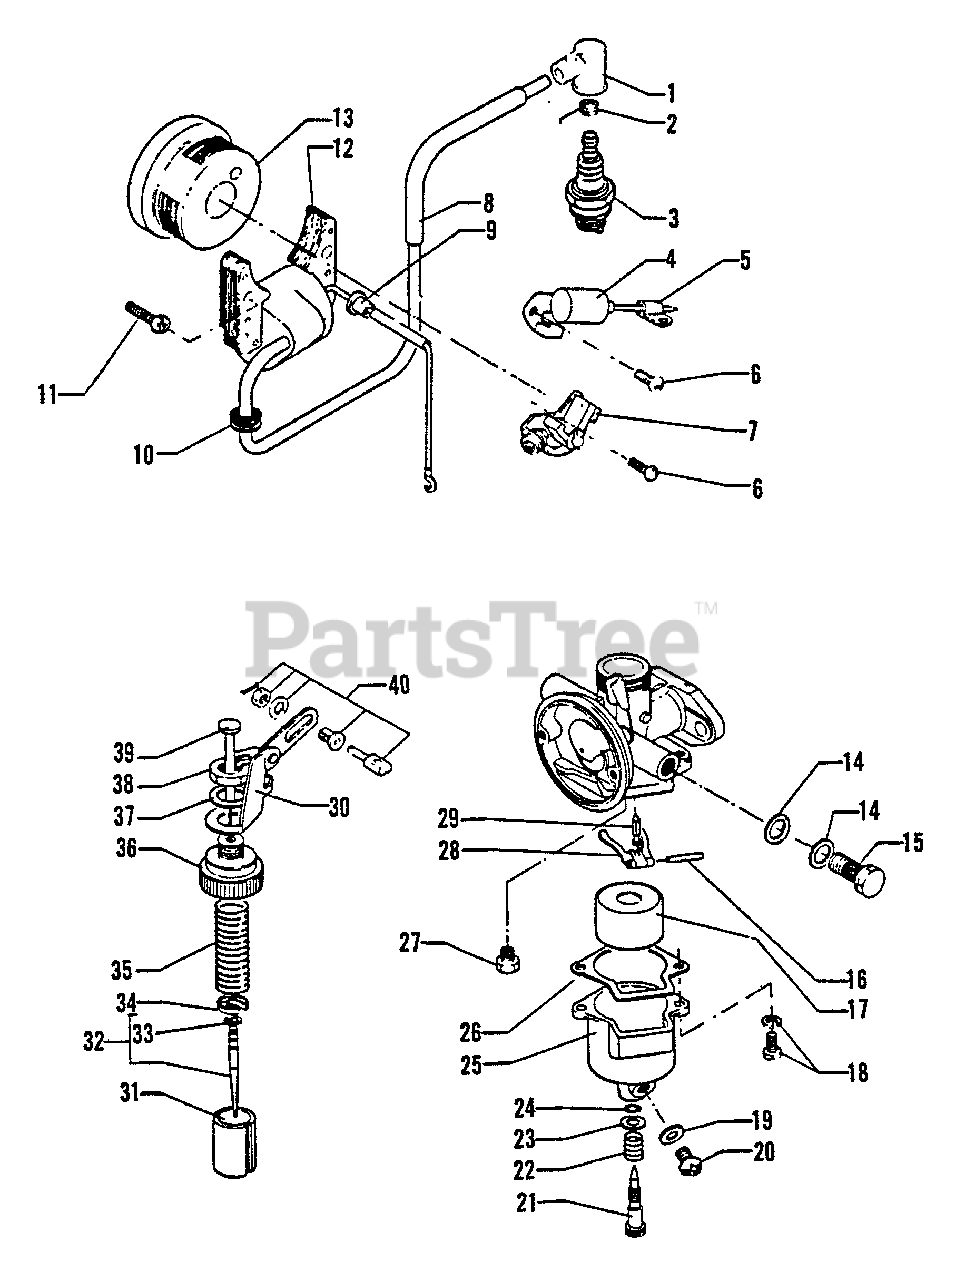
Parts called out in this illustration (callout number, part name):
1	CAP, SPARK PLUG
2	TERMINAL, SPARK PLUG CAP
3	SPARK PLUG -- BM-6A
4	CONDENSER
6	SCREW - 4X10
7	CONTACT POINT SET
11	SCREW - 5X25
12	COIL, IGNITION
13	FLYWHEEL
15	BOLT, BANJO
16	PIN, METERING LEVER
17	FLOAT
18	SCREW - 4X14
19	GASKET, DRAIN
20	SCREW - 4X6
21	NEEDLE, METERING
22	SPRING, METERING LEVER
23	WASHER
24	O-RING
25	CHAMBER, FLOAT
26	GASKET, FLOAT CHAMBER
27	JET, MAIN
28	LEVER, METERING
29	VALVE, INLET NEEDLE
30	LEVEL ASSY
31	VALVE, THROTTLE
32	VALVE, INLET NEEDLE
33	RING, RETAINING
34	SEAT, SPRING
35	SPRING, THROTTLE
36	COVER - TOP
37	WASHER
38	NUT
39	BAR, LINK
40	CONNECTOR
